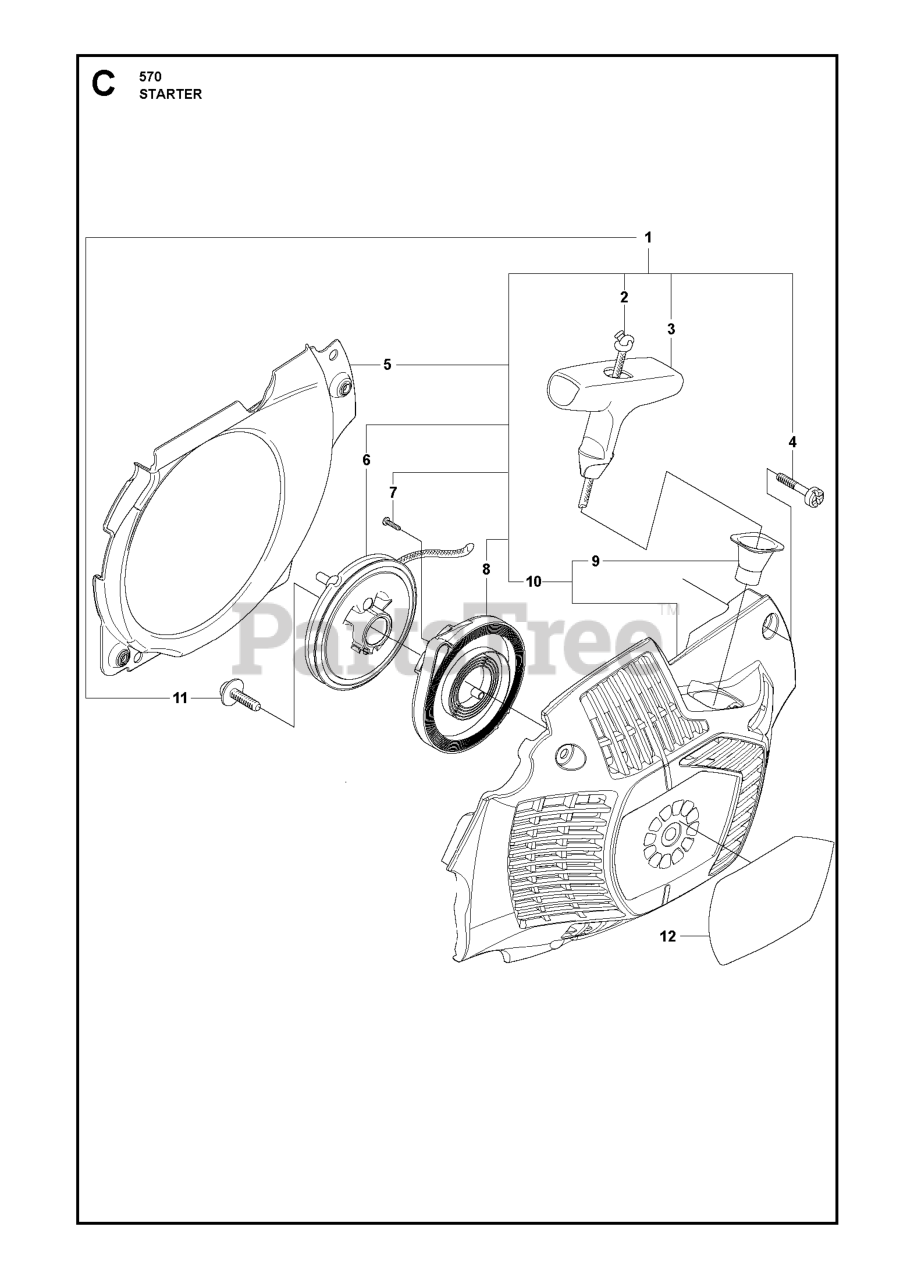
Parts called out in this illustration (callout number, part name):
1	STARTER ASSY
2	STARTER ROPE
4	SCREW.CIHPANMO M5X19 10.9
6	STARTER PULLEY
8	RP SPRING
10	STARTER HOUSING
